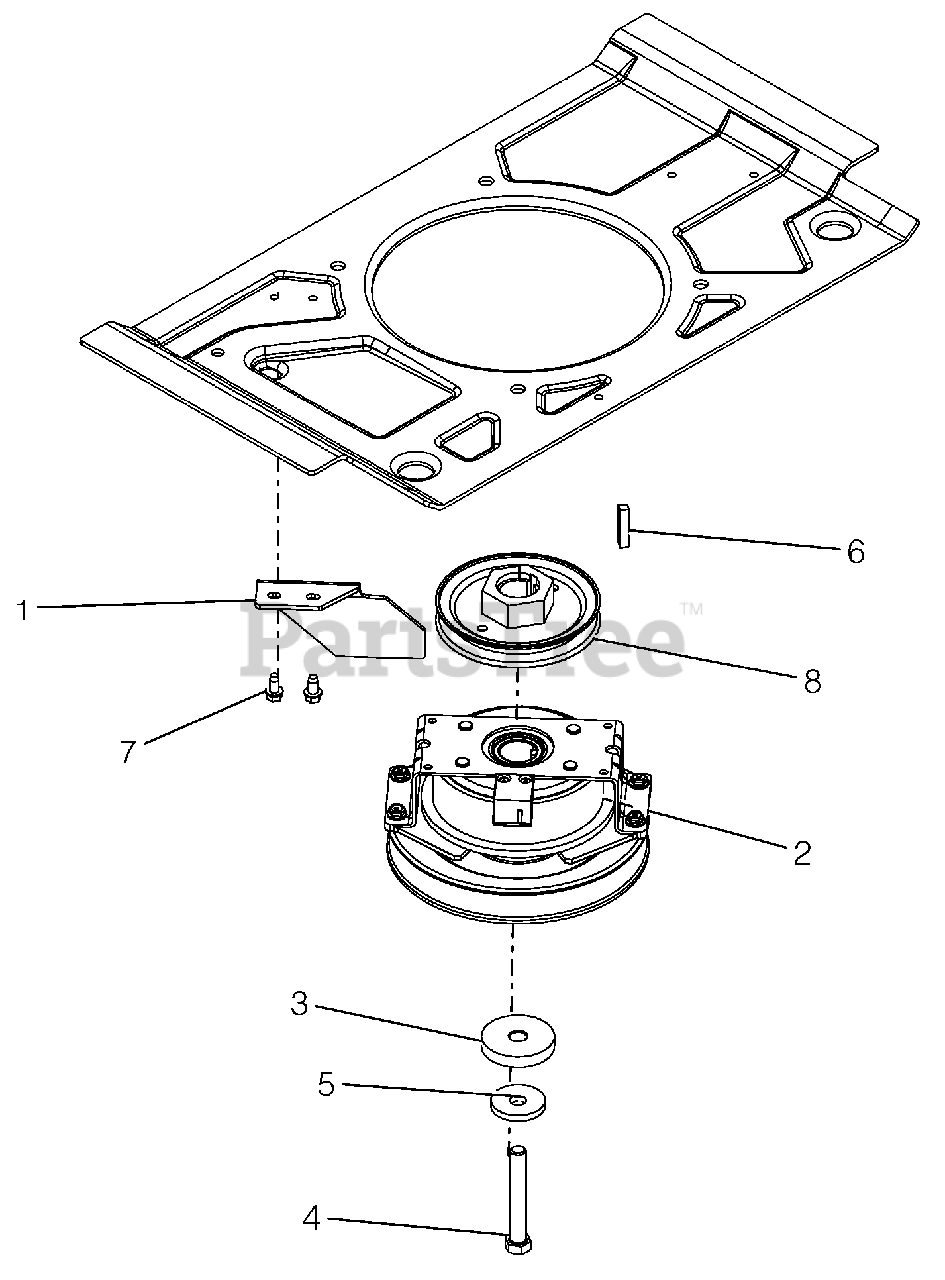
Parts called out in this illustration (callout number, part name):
1	BRKT, CLUTCH STOP HD
2	CLUTCH, OGURA DBL SPRG
3	SPACER, .474/.459X2.00X.350
4	BLT-HEX .44-20X3 G8YZ NYTORQ
5	WASHER, 7/16" SPRING DISK
6	KEY-SQ .25 X 1.25 X .25 SAE
7	SCR-TAP .25-20X.50 HWH TR YWZ
8	WLDMT,PULLEY-4.50ODX1.003
